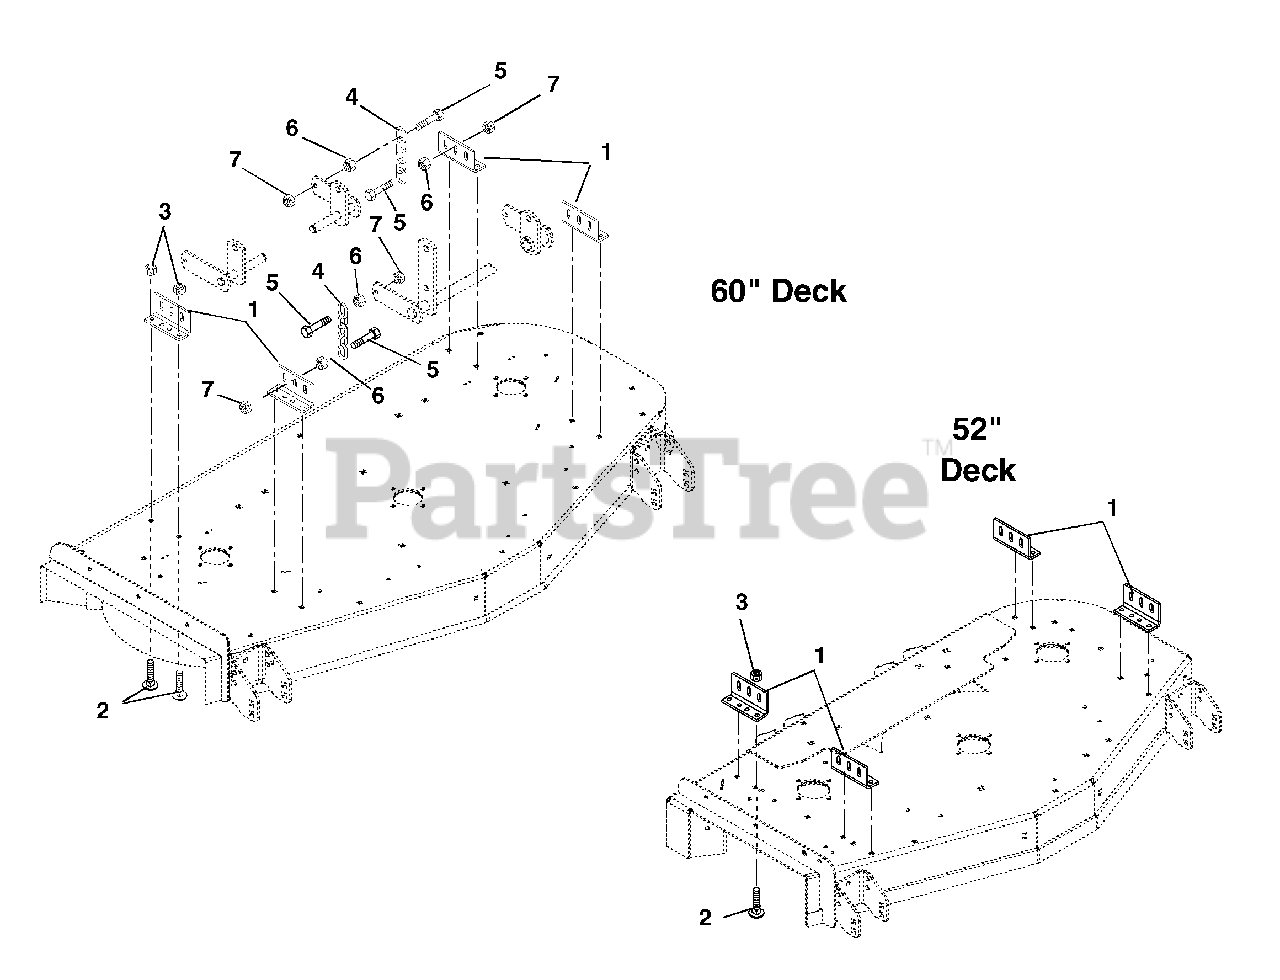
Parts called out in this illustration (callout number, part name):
1	MOWER MOUNTING BRACKET - RED
2	@BLT-RDHDSQNK .38-16X1.00 G5YZ
3	@NUT-LK-TOP-FLG .38-16 YWZC
4	CHAIN, LINK
5	@BLT-HEX .50-13X2.00 GR5 YWZC
6	NUT-SPNLK-FLG .50-13 YWZC
7	@NUT-LK-TOP-FLG .50-13 YWZC
